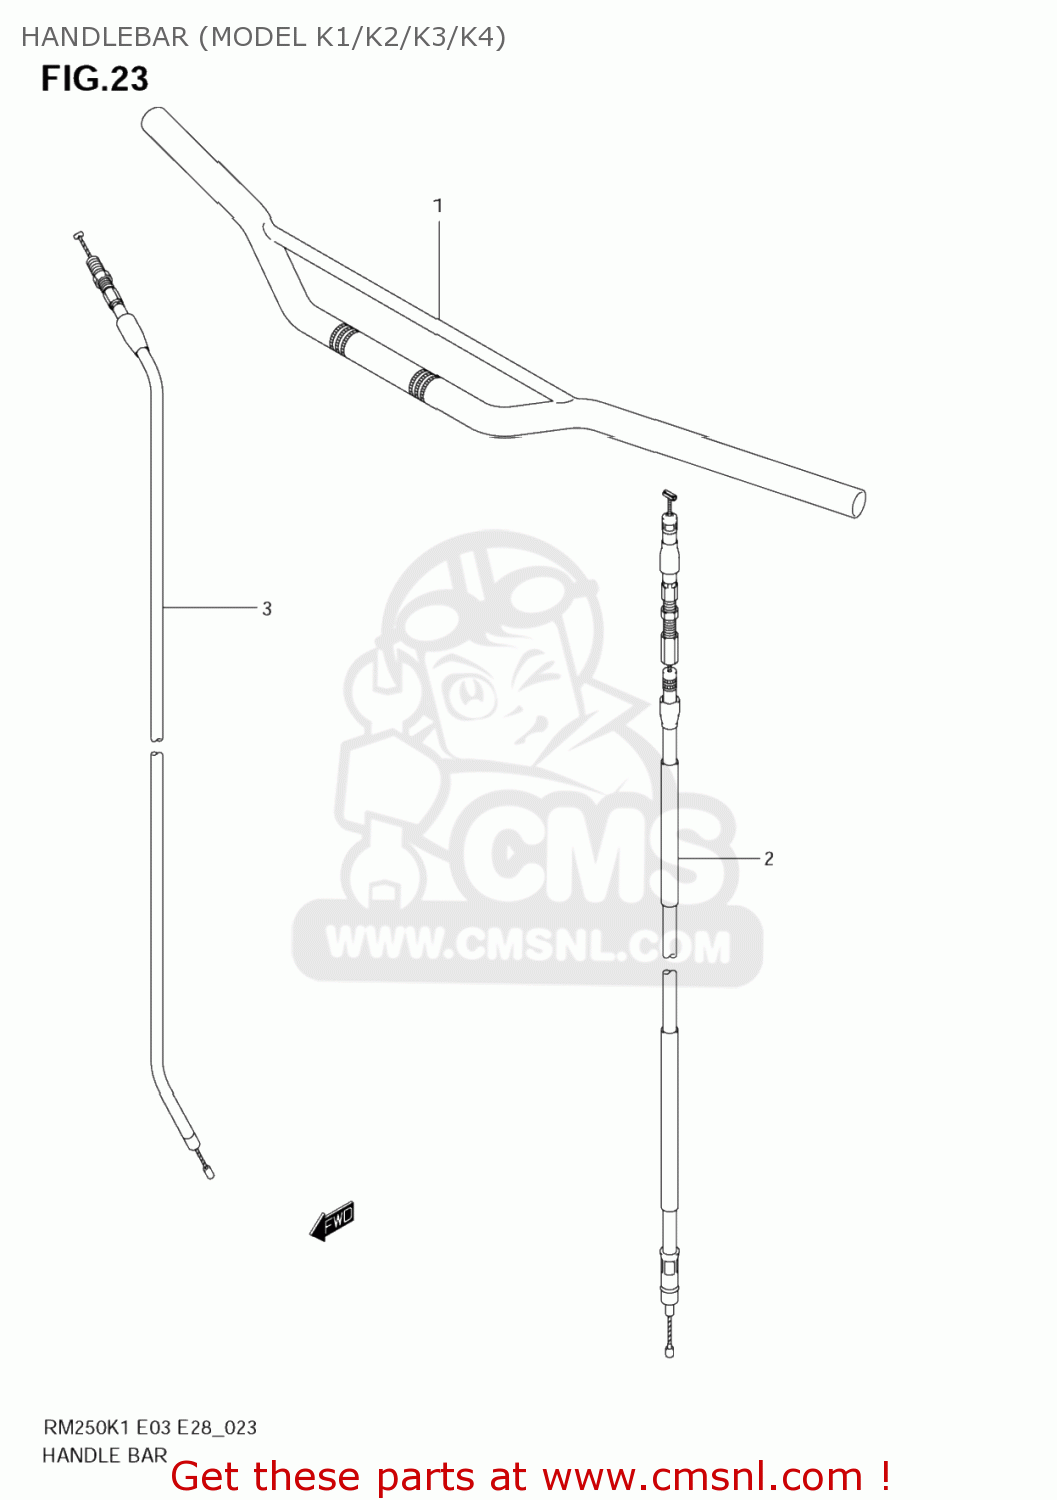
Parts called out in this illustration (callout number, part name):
1	HANDLEBAR(SILVER)
2	CABLE ASSY,CLU
3	CABLE ASSY,THROTTLE
